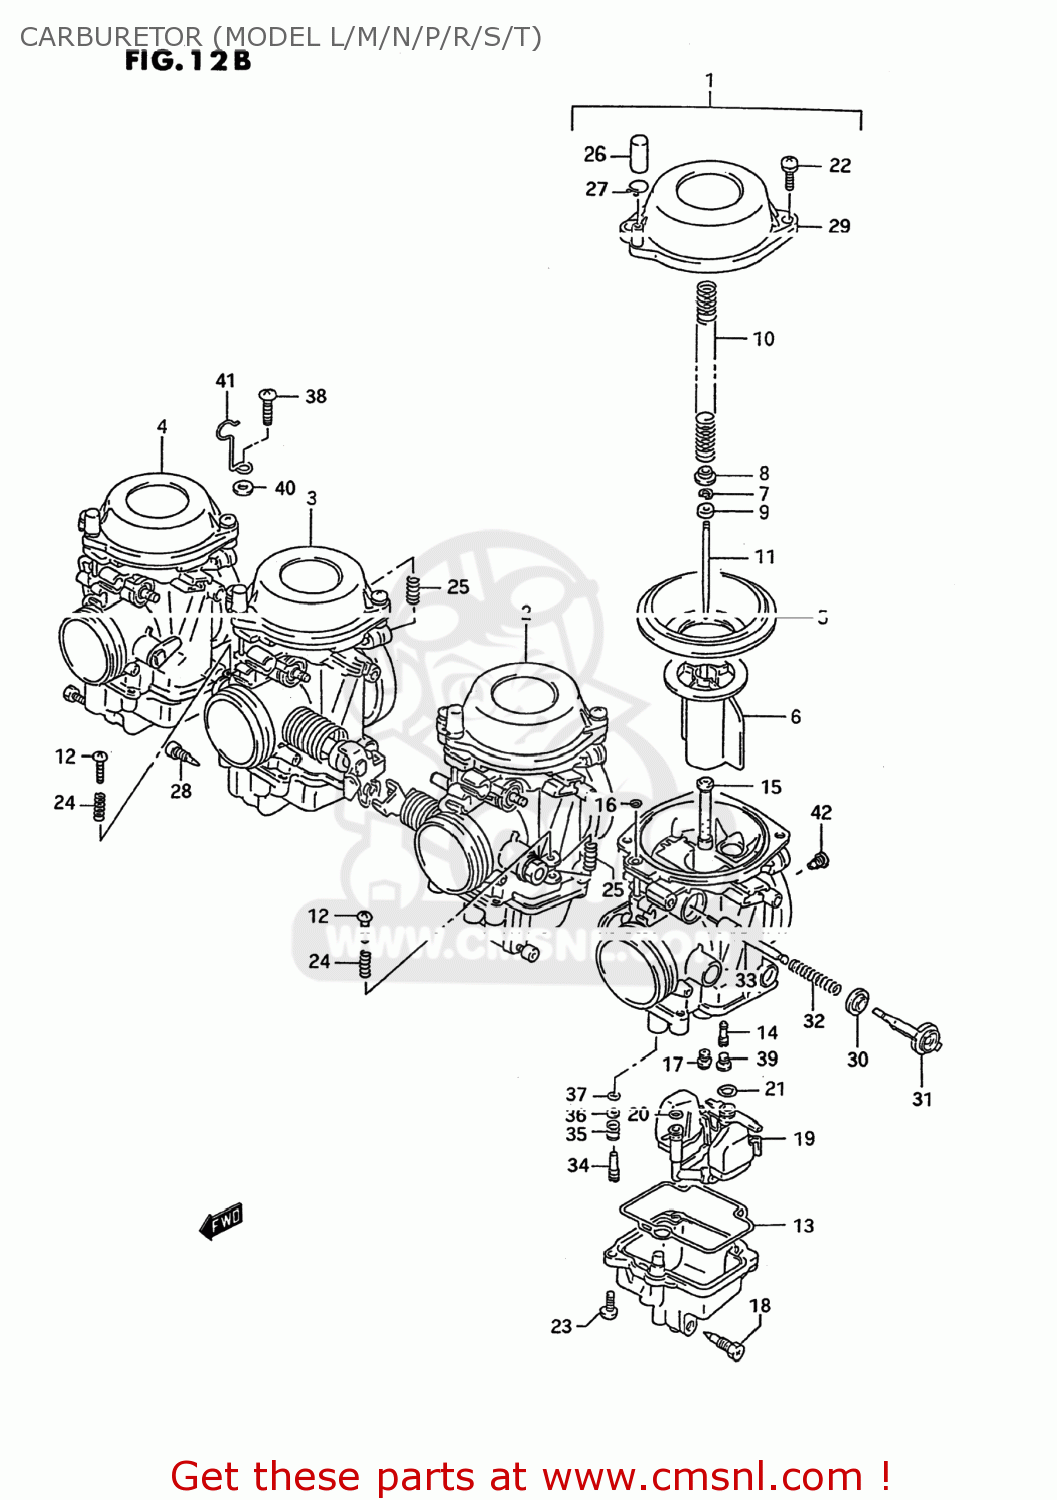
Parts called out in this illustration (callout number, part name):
1	CARBURETOR ASSY
2	CARBURETOR.ML
3	CARBURETOR.MR
4	CARBURETOR.RH
5	DIAPHRAGM
6	VALVE,PISTON
7	E RING
8	RING
9	RING
10	SPRING
11	NEEDLE,JET
12	SCREW
13	GASKET,FLOAT CHAMBER (NAS)
14	JET,PILOT(32.5)
15	JET,NEEDLE(P-3)
16	O RING
17	JET,MAIN(110)
18	PLUG,DRAIN
19	FLOAT/NEEDLE VALVE ASSEMBLY
20	O RING
21	O-RING,NEEDLE VALVE
22	SCREW
23	SCREW
24	SPRING
25	SPRING
26	CAP
27	CLIP
28	SCREW,DRAIN
29	COVER,DIAPHRAGM
30	CAP,STARTER
31	HOLDER,GUIDE
32	SPRING
33	PLUNGER ASSY
34	SCREW,PILOT
35	SPRING
36	WASHER
37	O RING,PILOT AIR SCREW
38	SCREW
39	PLUG
40	WASHER
41	CLIP
42	JET,AIR(1.3)
